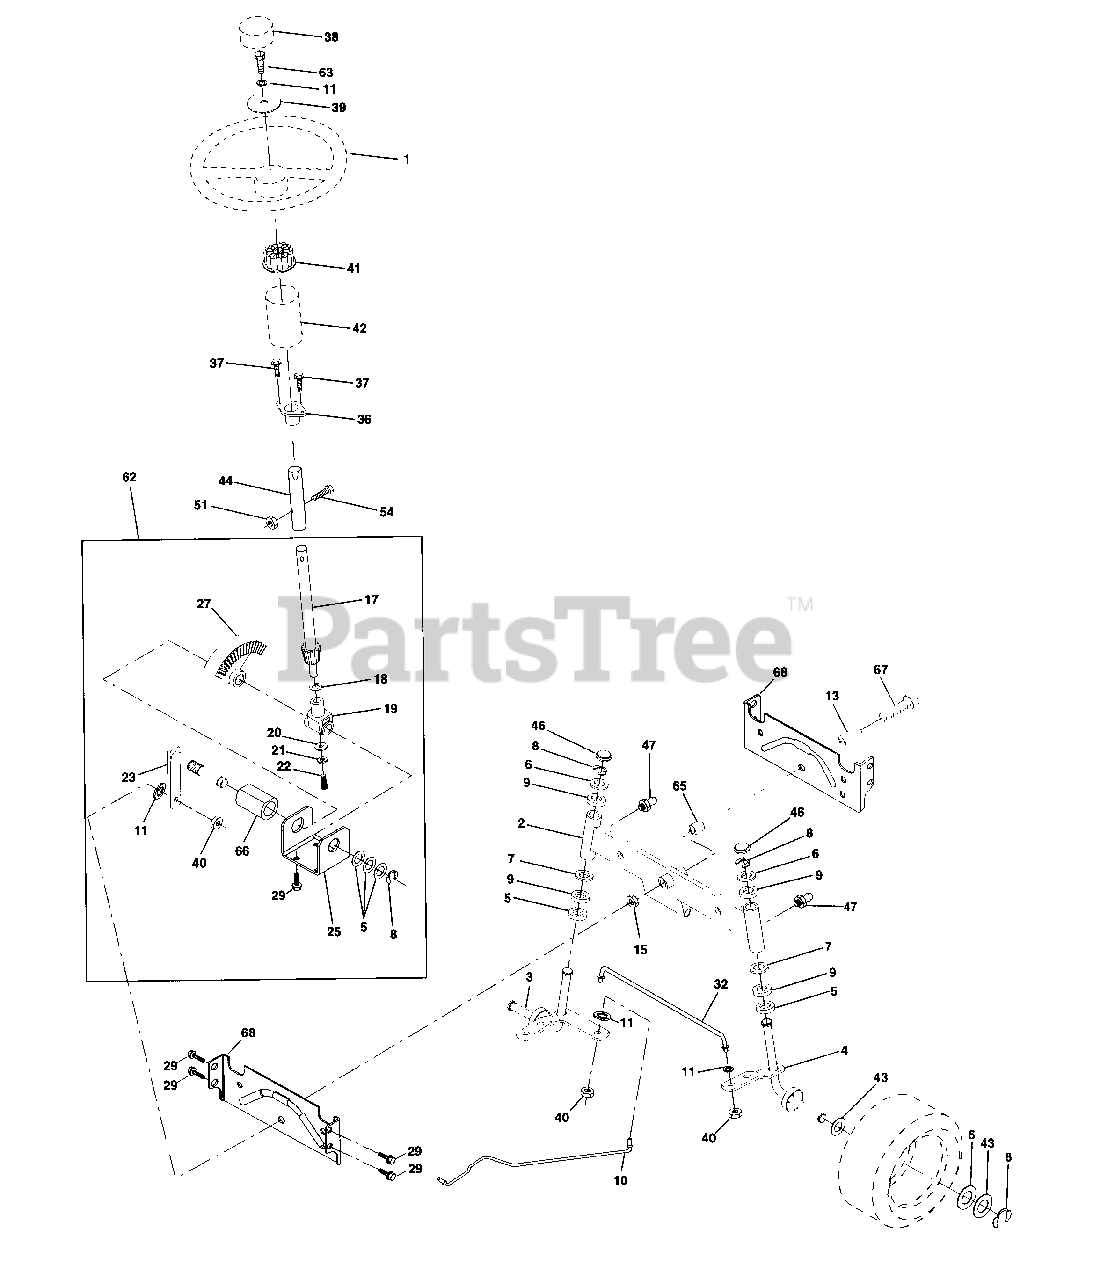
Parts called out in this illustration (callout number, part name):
1	Wheel Steering
2	Axle Front Casting Machined
3	Spindle Asm LH Cast 15"
4	Spindle Asm RH Cast 15"
5	Bearing Race Thrust Harden
6	Washer 25/32 x 1-5/8 x 16 Ga
7	Washer 27/32 x 1-1/4 x 16 Ga
8	Ring Klip #t5304-75
9	Bearing Col Strg Blk
10	Link Drag Extended Cast
11	Washer Lock Hvy Hlcl Spr 3/8
13	Bearing Axle STLT/GT
15	Nut Lock Flange 5/8-11 Unc
17	Shaft Asm Strg
18	Washer Thrust 515 x 750 x 033
19	Support Shaft
20	Washer Shim 1/4 x 5/8 x 062
21	Washer Lock Hvy Helical 1/4
22	Screw Cap Sckt Hd Phos & Oil
23	Shaft Asm Pittman
25	Bracket Steering
27	Gear Sector
29	Screw Thdrol 3/8-16 x 3/4 Ty-tt
32	Rod Asm Tie Ball J Adj VGT
36	Bushing Strg
38	Insert Cap Strg Wh Au
39	Washer 13/32 x 2-3/8 x 8 Ga
40	Lock nut
41	Adaptor Wheel Strg
42	Boot Steering Shaft
43	Washer 25/32 x 1-1/4 x 16 Ga
44	Extension Steering Shaft LR/LT
46	Cap Spindle Fr Top Blk
47	Fitting Grease
51	Nut Lock Hex w/Ins 5/16-18
54	Bolt Fin Hex 5/16-18 Unc x 1-1/4
62	Kit, Steering Assembly Svc
63	Bolt Fin Hex 3/8-16unc x 1 Gr. 5
65	Spacer Axle
66	Bearing Arm Pittman
67	Bolt, Fin Hex 5/8-11 UNC x 2-3/4
68	Axle, Brace
